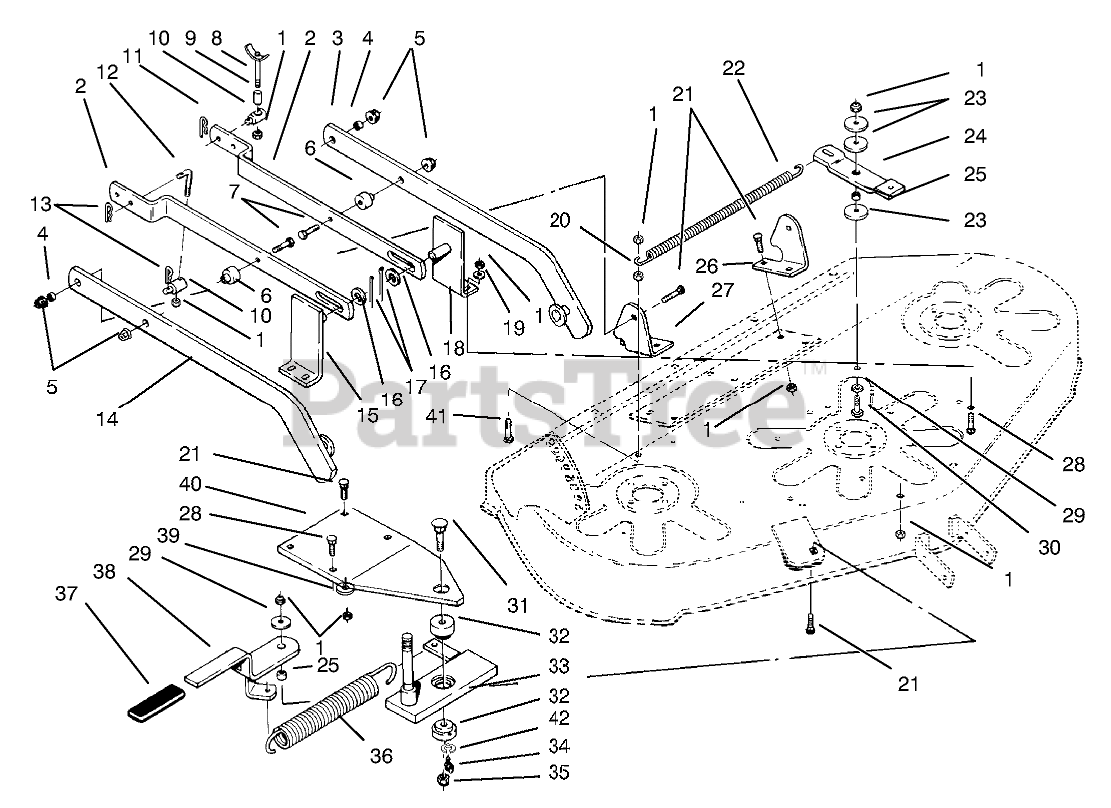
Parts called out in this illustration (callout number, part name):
1	NUT-LOCK, NI
2	Bar-Leveler
3	Draft Bar LH
4	SPACER
5	LOCKNUT-FLANGE
6	SPACER
7	SCREW-HH
8	WLDMT-HANGER ROD
9	Spacer
10	TRUNNION
11	PIN-HAIR
12	ROD-LIFT
13	PIN-COTTER
14	Draft Bar RH
15	Bracket RH
16	WASHER-FLAT
17	PIN-COTTER
18	Bracket
19	WASHER-FLAT
20	NUT-HEX
21	BOLT-CARR
22	SPRING - EXTENSION
23	WASHER
24	Arm-Idler
25	SPACER
26	Bracket LH
27	Bracket RH
28	BOLT-CARR
29	WASHER
30	SCREW-HH
31	SCREW-CARR
32	BUSHING
33	Countershaft
34	FITTING GREASE
35	NUT-LOCK, NI
36	Spring
38	Lever
39	WASHER-SPACER
40	Plate
41	SCREW-HH
42	WASHER-LOCK
